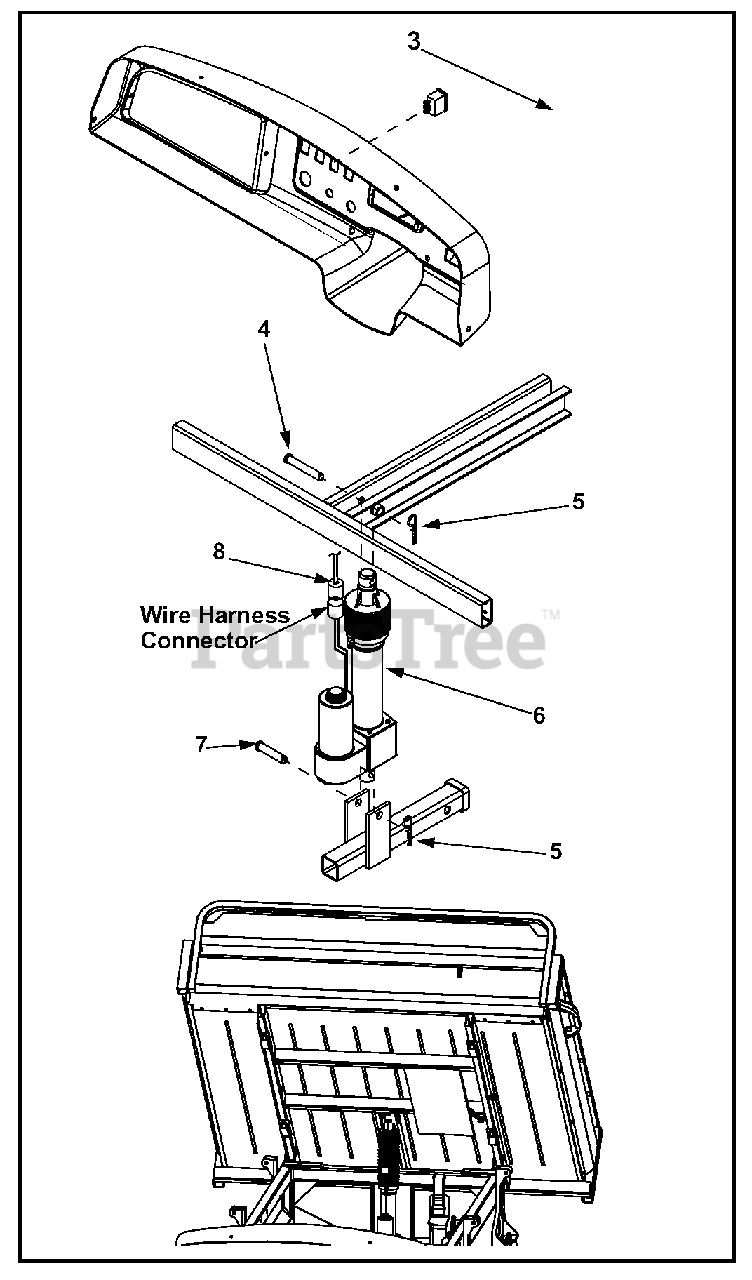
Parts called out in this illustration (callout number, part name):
1	Fuse 30 Amp
2	Relay 12V 40A (2)
3	Cargo Box Switch
4	Clevis Pin 3.0"
5	Internal Cotter Pin
6	Electric Lift Actuator
7	Clevis Pin 2.25"
8	Pigtail, Harness
